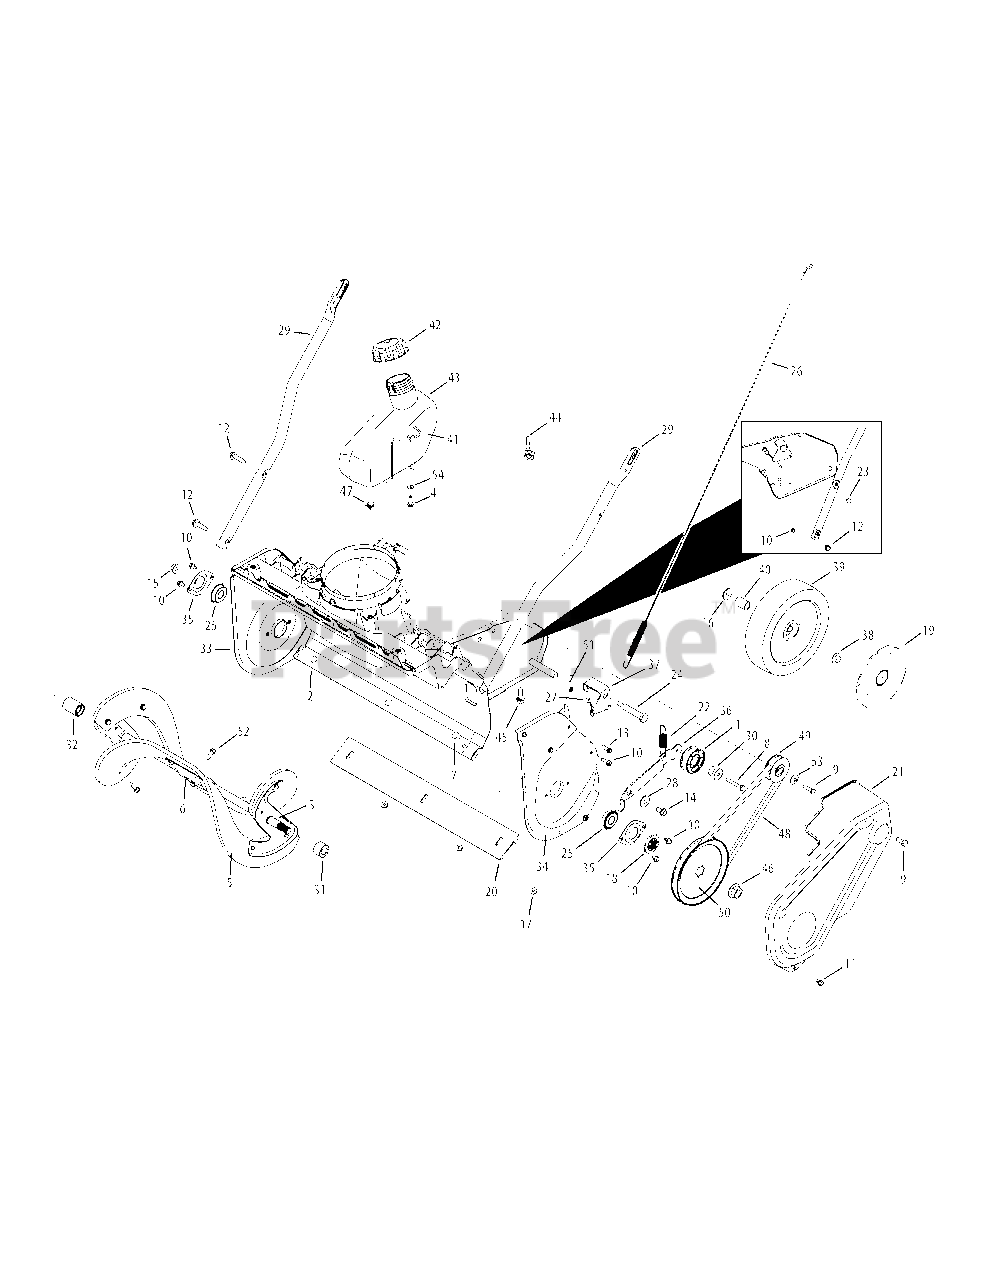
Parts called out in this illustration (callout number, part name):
1	Idler Pulley Assembly
2	Frame
3	Auger Assembly Mount
4	Screw, 1/4-10 x .625
5	Auger Replacement Kit
6	Center Auger Bracket
7	Carriage Screw, 1/4-20 x .62
8	Hex Screw, 1/4-20 x 1.50
9	Hex Lock Screw, 5/16-24 x .750
10	Hex Washer Screw, 1/4-20 x .625
11	Hex Washer Screw, 1/4-20 x .500
12	Hex Washer Screw, 5/16-18 x 1.250
13	Hex Washer Screw, 1/4-15 x .750
14	Hex Washer Screw, 5/16-18 x .75
15	Flange Lock Nut, 3/8-16
16	Flat Washer, .535 x .930 x .090
17	Flange Lock Nut, 1/4-20
18	Pulley Hub
19	Hubcap
20	Shave Plate
22	Extension Spring, .70 x 3.035
23	Hex Screw, 5/16-24 x 1.25
24	Shoulder Bolt, 5/16-24 x .496 x 2.18
25	Ball Bearing, .500 x 40mm x 12mm
26	Clutch Cable
27	Drive Cable Wire Support
28	Shoulder Spacer
30	Shoulder Spacer, .260 x .785 x .538
31	LH Auger Spacer
32	RH Auger Spacer
33	RH Auger Plate
34	LH Auger Plate
36	Idler Bracket
38	Push Cap, 1/2
39	Wheel, 8 x 2 (Gray)
39	Wheel, 7 x 2 (Black)
40	Spacer, .525 x .775 x .835
41	Gas Tank Wire Support
42	Fuel Cap
43	Fuel Tank
44	Choke Extension Lever
45	Hex Washer Screw, 3/8-16 x 1.000
46	Flange Nut, 7/16-20
47	Hose Clamp
48	Belt, .500 x 35.06
49	Pulley Half, .625 x 2.25
50	Pulley, 1/2 x 6.00
52	Hex Washer Screw, 1/4-20 x .750
53	Thrust Washer, .330 x 1.25 x .120
54	Washer, .265 x 1.00 x .030
